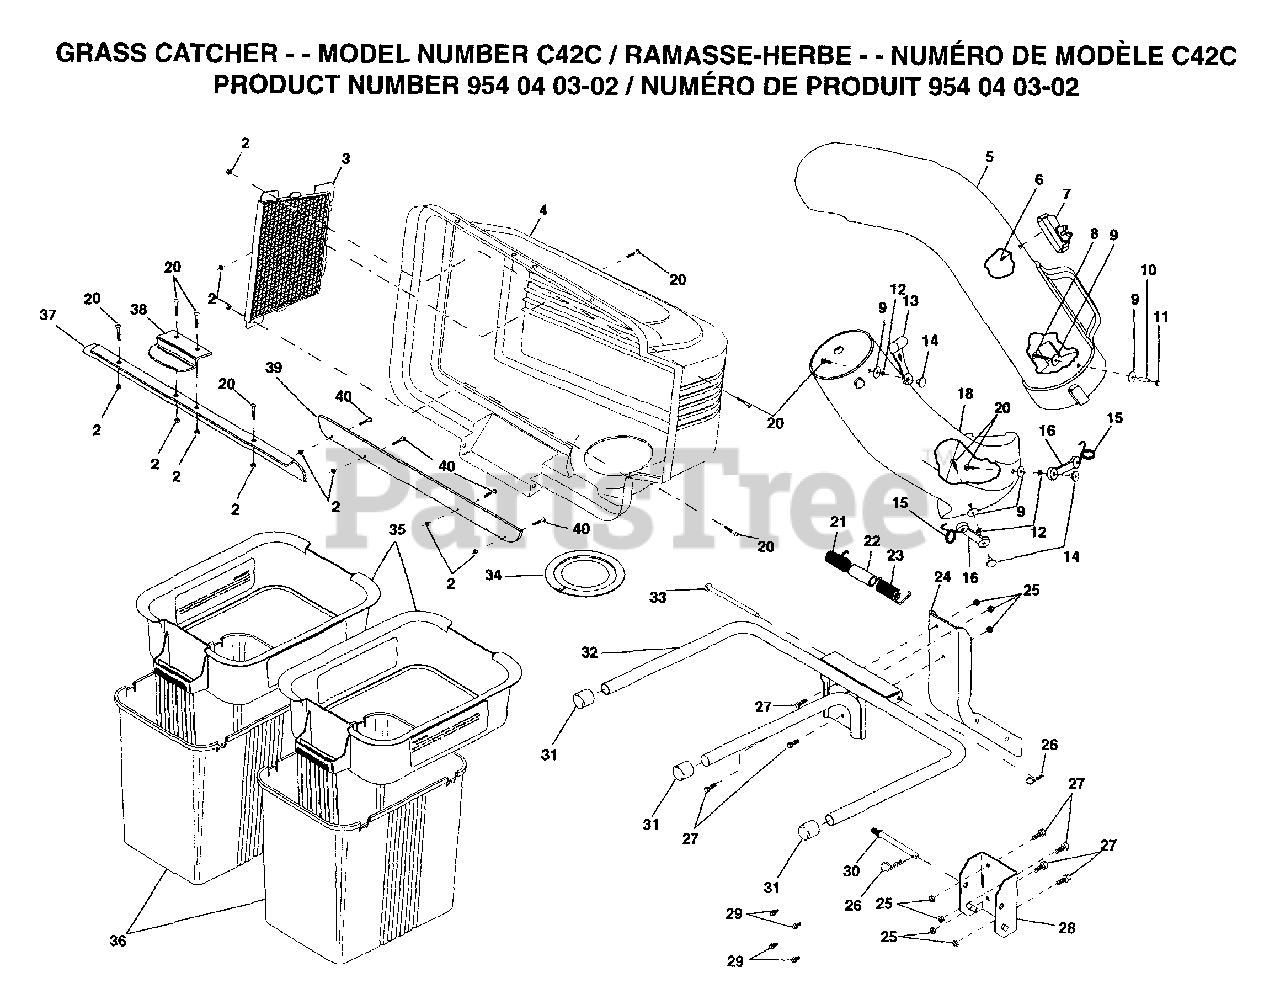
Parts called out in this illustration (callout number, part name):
2	NUT, CROWNLOCK #10-24
6	SCREW, SPECIAL #10-14X1/2
9	WASHER 3/16X3/4X16 GA
20	SCREW#10-24 X 5/8
27	BOLT, HEX 5/16-18 X 3/4
29	SCREW, 5/16-18 X 1/2 HEX, SELF TAPPING
40	SCREW #10-24 X 1/2
